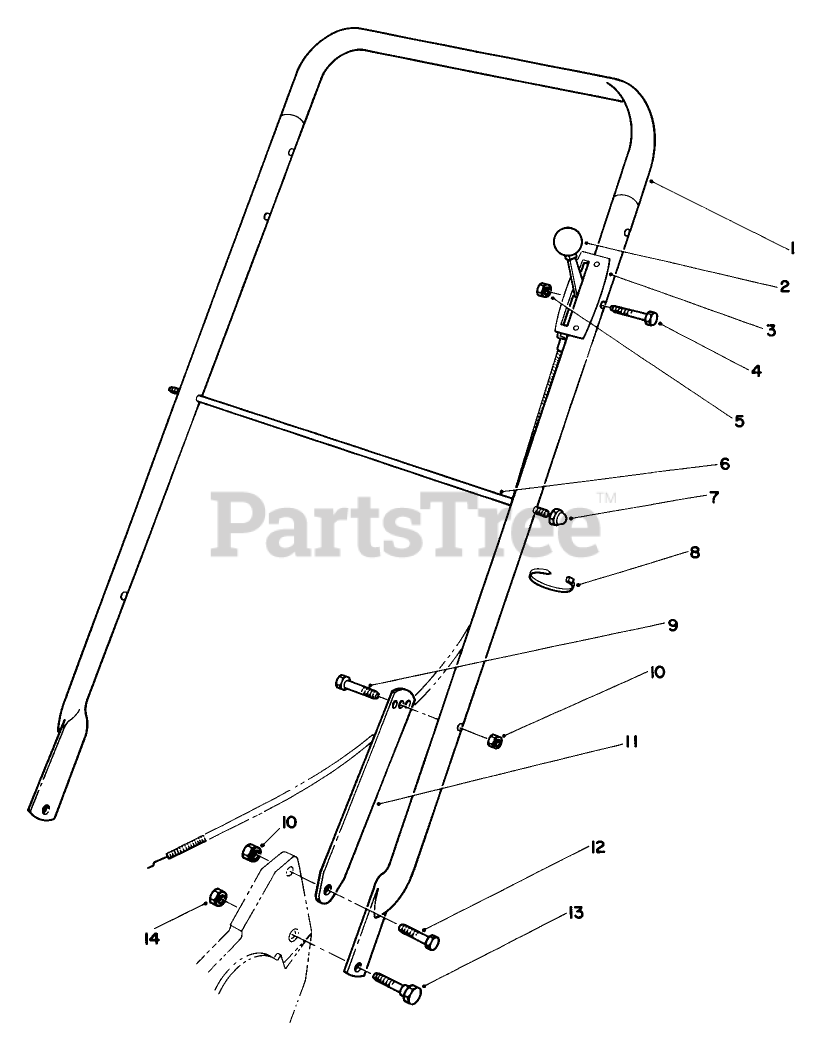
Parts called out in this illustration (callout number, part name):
2	KNOB-CONTROL
3	THROTTLE CONTROL
4	SCREW-HH
5	NUT-LOCK, NI
6	ROD-SUPPORT, BAG
7	NUT-CAP
8	TIE-CABLE
9	SCREW-HH
10	NUT-LOCK, NI
12	SCREW-HH
13	SCREW-SHOULDER
14	NUT-LOCK, CONE
